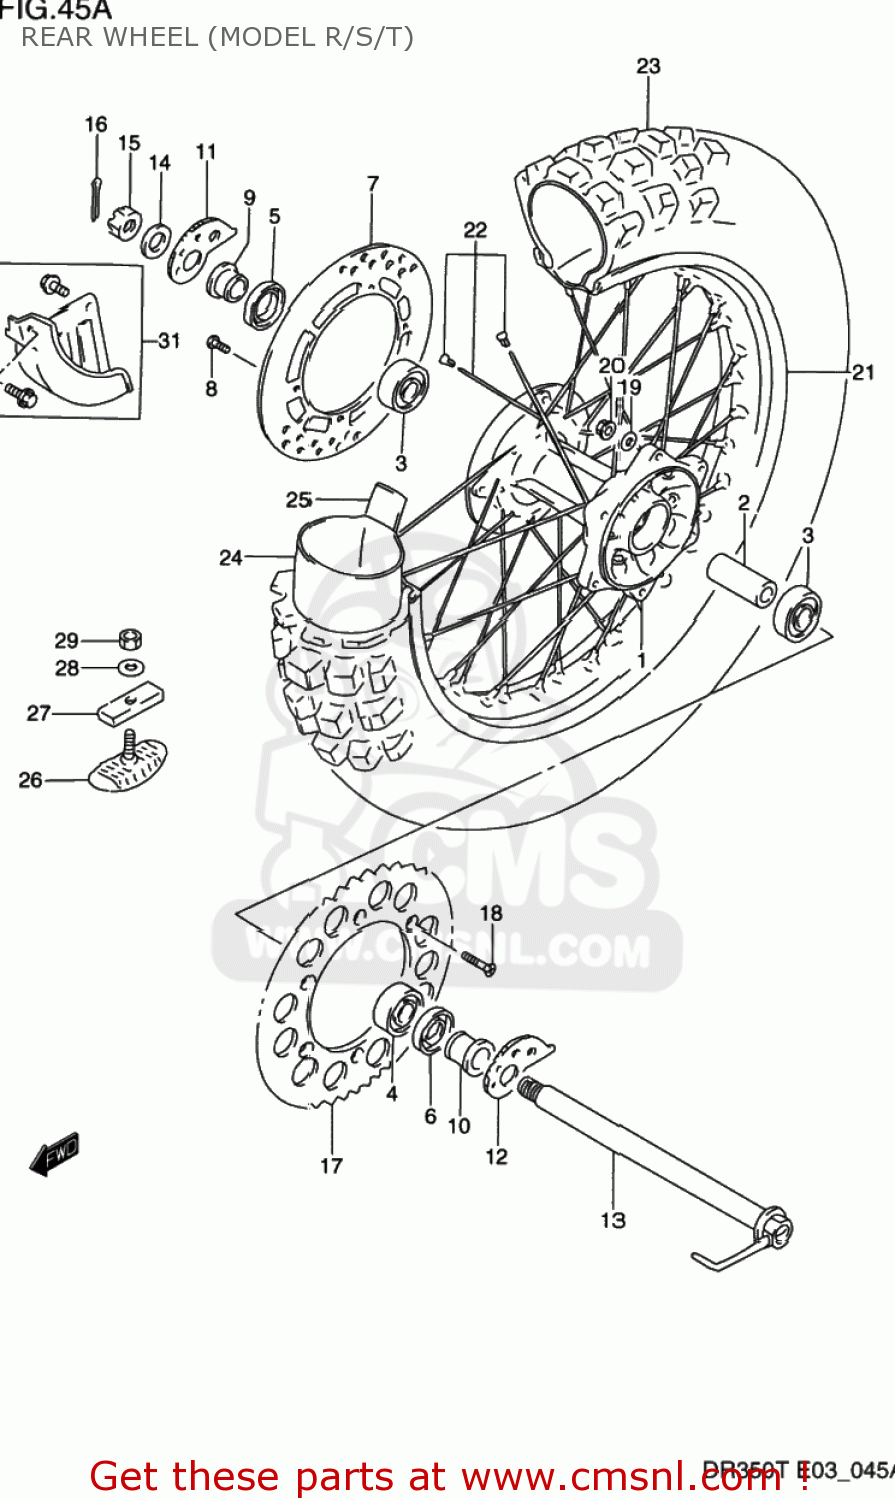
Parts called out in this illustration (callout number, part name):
1	HUB,REAR WHEEL
2	SPACER,RR HUB BEARING
3	BALL BEARING
4	BEARING
5	SEAL,OIL(26X42X8)
6	SEAL,OIL(26X47X5)
7	DISC,RR BRAKE
8	BOLT
9	SPACER,RR AXLE,R
10	SPACER,RR AXLE,L
11	ADJUSTER,CHAIN,R
12	ADJUSTER,CHAIN,L
13	AXLE,RR
14	WASHER(19X32X3.2)
15	NUT
16	PIN,COTTER
17	SPROCKET,RR(NT:43)
18	SCREW(8X33.5)
19	WASHER
20	NUT
21	RIM,RR WHEEL(18X2.15 AL)
22	SPOKE SET,RR WHEEL
23	TIRE COMP,REAR 110/100-1
24	TUBE,INNER
25	PROTECTOR,INNER TUBE
26	STOPPER,BEAD
27	CUSHION,BEAD STOPPER
28	WASHER
29	NUT
31	COVER SET,RR BRAKE DISC
